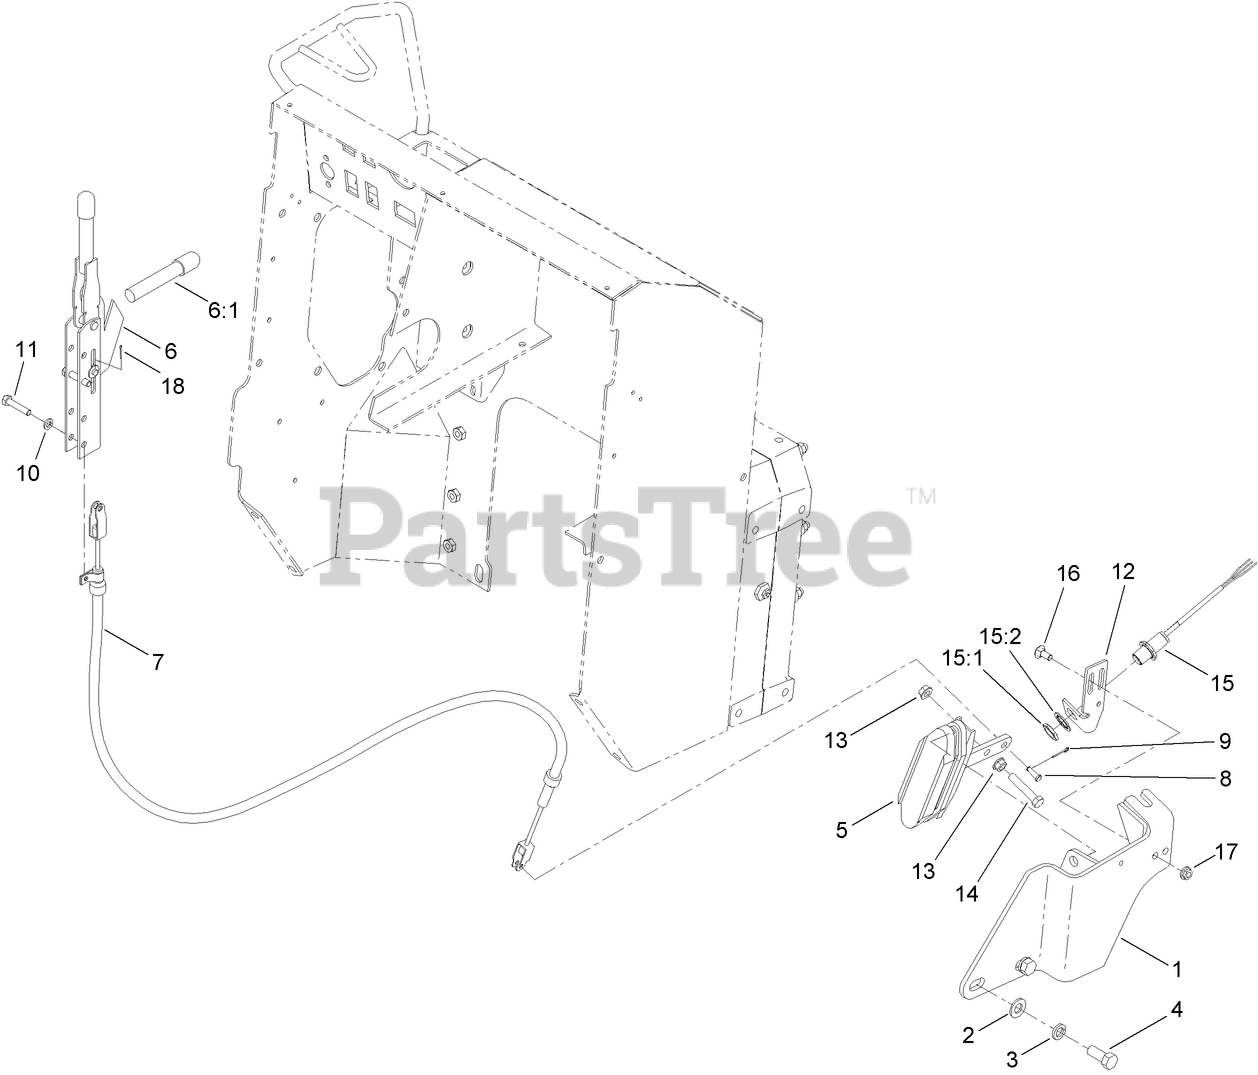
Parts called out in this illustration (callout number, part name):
1	BRACKET-BRAKE
2	WASHER-FLAT
3	WASHER-LOCK
4	SCREW-HH
5	CALIPER ASM
6	LEVER-BRAKE
6:1	SPACER
7	CABLE-BRAKE
8	PIN-CLEVIS
9	PIN-COTTER
10	WASHER-LOCK
11	SCREW-HH
12	BRACKET-SENSOR
13	NUT-HHF, WHIZ
14	SCREW-HH
15	PROXIMITY SENSOR ASM
15:1	NUT-HEX
15:2	WASHER-LOCK, INTERNAL TOOTH
16	BOLT-CARR
17	NUT-HF
18	PIN-COTTER
